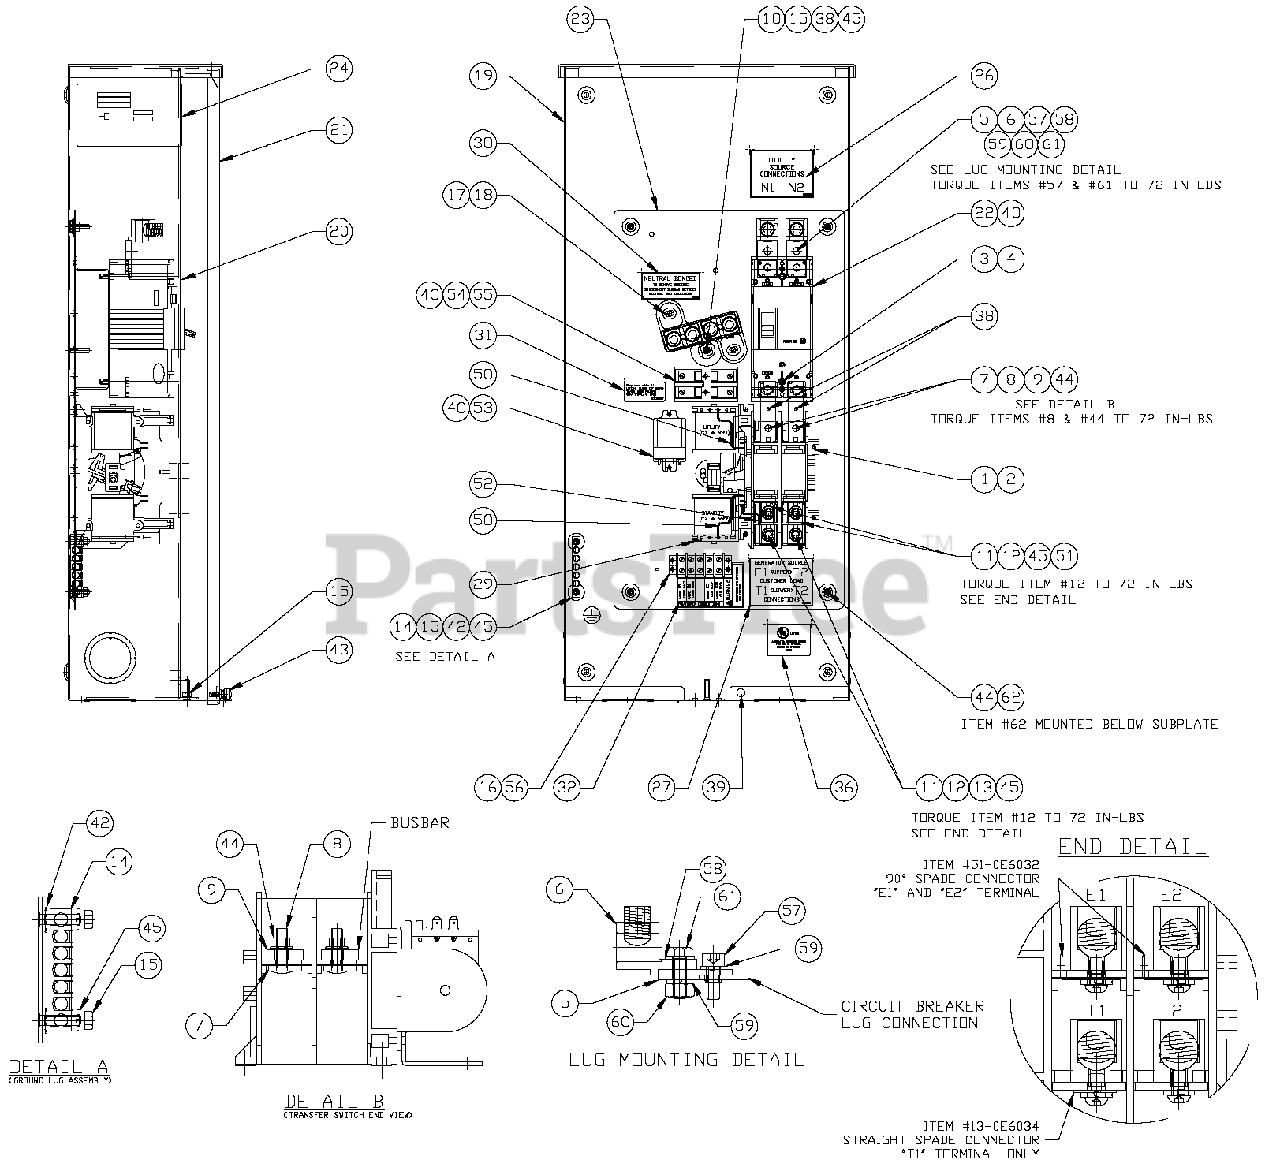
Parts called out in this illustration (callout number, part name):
1	TRANSFER SW. HSB 200A 2P 250V
2	SCREW HHTT M5-0.8 X 10 BP
3	CIRCUIT BREAKER, 200A 2-POLE
4	SCREW RHM #8-32 X 3-1/4
5	BUSBAR, 200A LUG ADAPTER
6	LUG 300 MCM-6STR
7	SPACER 200 AMP TRANSFER
8	BOLT CARR 1/4-20 X 1"
9	BUSBAR, 200A TRANSFER SW N1,N2
10	BUSBAR, NEUTRAL BLOCK
11	LUG SOLDERLESS 250-#6 AL/CU
12	SCREW BHSC 1/4-20 X 3/8
13	STRAIGHT SPADE CONNECTOR
14	GROUND BAR (5) 2-14 AWG CONN
15	NUT HEX 1/4-20 SS
16	RIVET, POP .156 X .67
17	ASSY-NEUT BLK 200-400A W/TAP
18	SCREW HHTT M6-1.0 X 12 MM
19	ENCLOSURE, 200A SE XFER SW
20	COVER, INSIDE 200A DUAL BREAKER
21	COVER, TRANSFER SWITCH
22	CB RISER BRACKET 200A GENERAC
23	SUBPLATE, 200A SE XFER SW
24	DECAL TRANSFER SWITCH DATA
26	DECAL, UTILITY SOURCE CONN
27	DECAL, GENERATOR/CUSTOMER CONN
29	DECAL, TRANSFER SWITCH INFO
30	DECAL, NEUTRAL CONNECTION
31	DECAL, FUSE REPLACEMENT
32	DECAL, TERMINAL STRIP
36	DECAL, UL LIST HSB
37	DECAL FRNT CVR ATS 3R SER DIS
38	SCREW HHTT #8-32 X 1/4 CZ
39	NUT TRIC 1/4-20 X .525
40	SCREW HHTT M4-0.7 X 10 BP
42	WASHER SHAKEPROOF EXT 1/4 STL
43	THUMB SCREW 1/4-20x1/2
44	NUT HEX FL WHIZ 1/4-20
45	WASHER LOCK M6-1/4
51	90 DEGREE UP SPADE CONNECTOR
52	WIRE-E1
53	RELAY PNL 12VDC DPDT
54	FUSEBLOCK 30A 600V 2 POLE
55	FUSE 5A X BUSS HLDR73591
56	BLOCK TERM 20A 5 X 6 X 1100V
57	SCREW SHC M8-1.25 X 20 G8
58	WASHER FLAT 5/16-M8 ZINC
58	WASHER LOCK M8-5/16
59	NUT HEX M8-1.25 G8 CLEAR ZINC
60	SCREW HHC M8-1.25 X 25 C8.8
61	SCREW HHTT #8-32 X 1/4 CZ
62	WASHER FLAT 1/4-M6 ZINC
